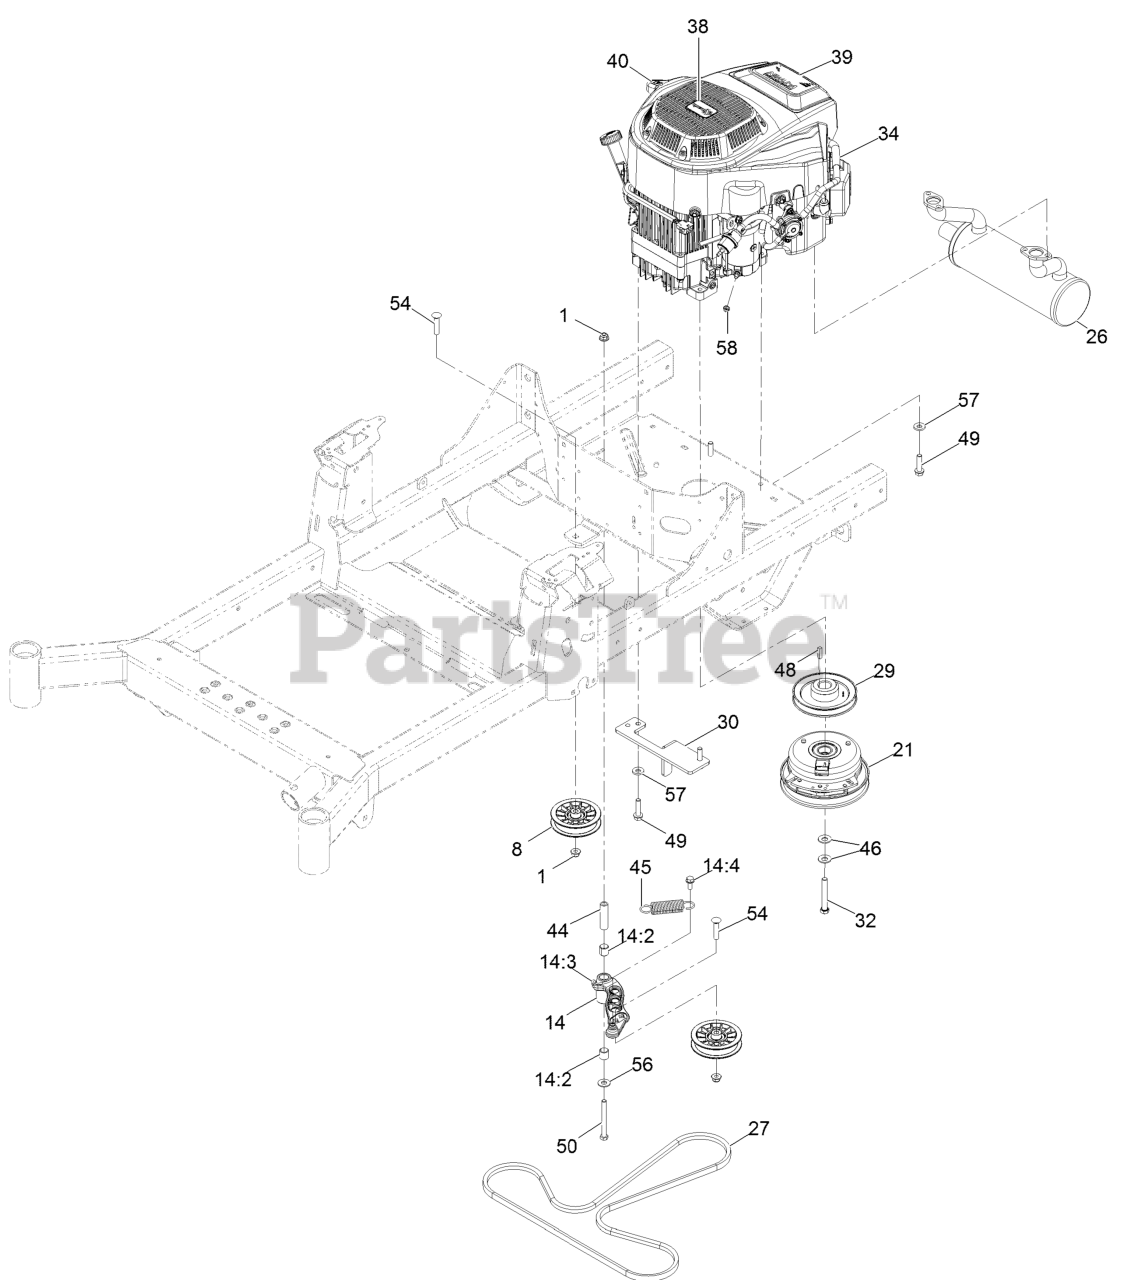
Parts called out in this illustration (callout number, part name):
1	Nut-Nyloc 3/8-16 Flg
8	Pulley-Flat
14	Idler Arm ASM
14:2	Sleeve-Bearing
14:3	Zerk-90deg 1/4-28
14:4	Screw-HWH 5/16-18 X 3/4 Tf
21	Clutch 1.00
26	Muffler
27	Belt-V
29	Sheave-Engine
30	Anchor-Clutch
32	Screw-HH 7/16-20 X 3 W/Loctite
34	Engine-2P77F
39	Decal-708Cc V-Twin Engine
40	Decal-Drain, Oil
44	Bushing-Pivot, Idler
45	Spring-Extension
46	Washer-Spring Disc 7/16
48	Key-Machine 1/4 X 1/4 X 1
49	Screw-HWH 3/8-16 X 1 1/2 Taptite
50	Screw-HH 3/8-16 X 3 1/2
54	Bolt-Carriage 3/8-16 X 1 3/4
56	Washer-3/8 Std
57	Washer-Spring Disc 3/8
58	Nut-Hex M6-1 Flg
